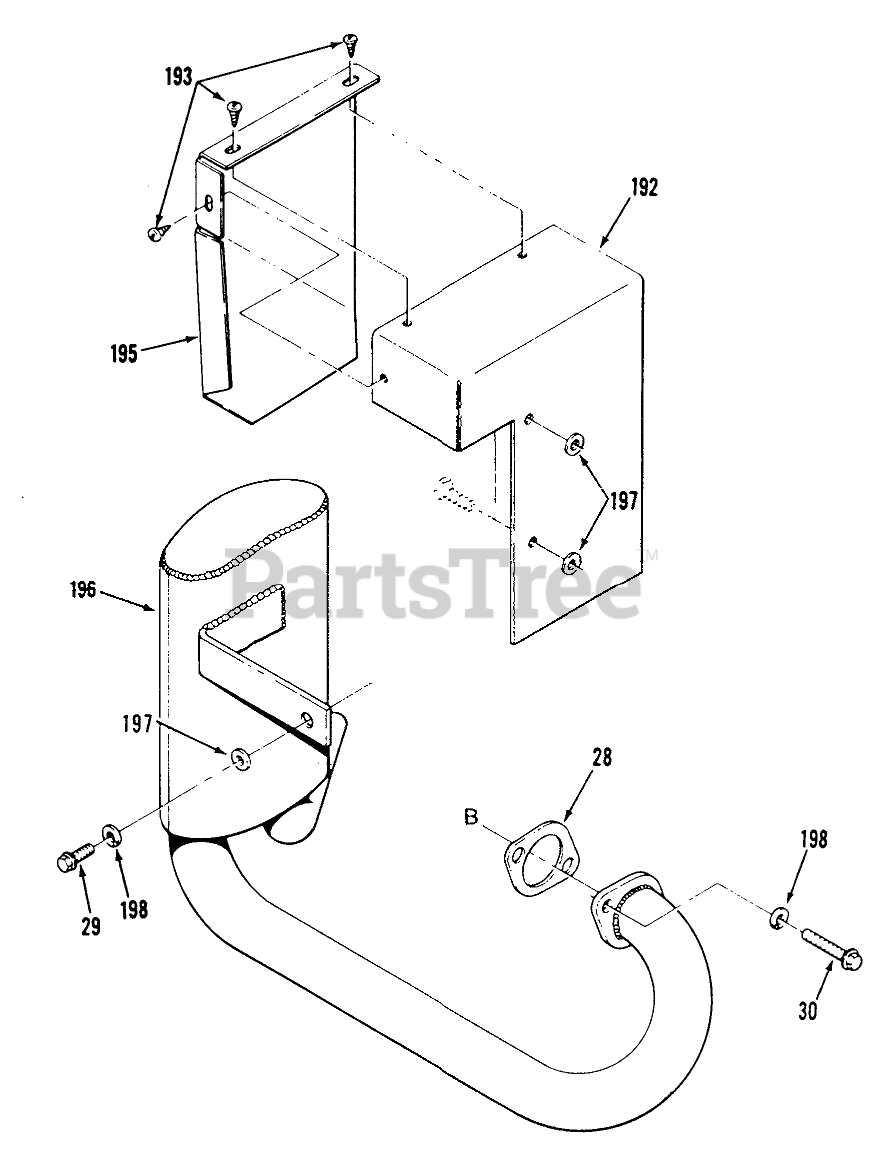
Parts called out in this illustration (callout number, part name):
28	GASKET
29	Flanged Bolt 8x14
30	Flanged Bolt 8x45
192	SHIELD-HEAT B
193	SCRW-HX S.T.#8 X 3/8
195	SHIELD-HEAT
196	Muffler-Black
197	WASHER 5/16 SAE
198	Lockwasher
